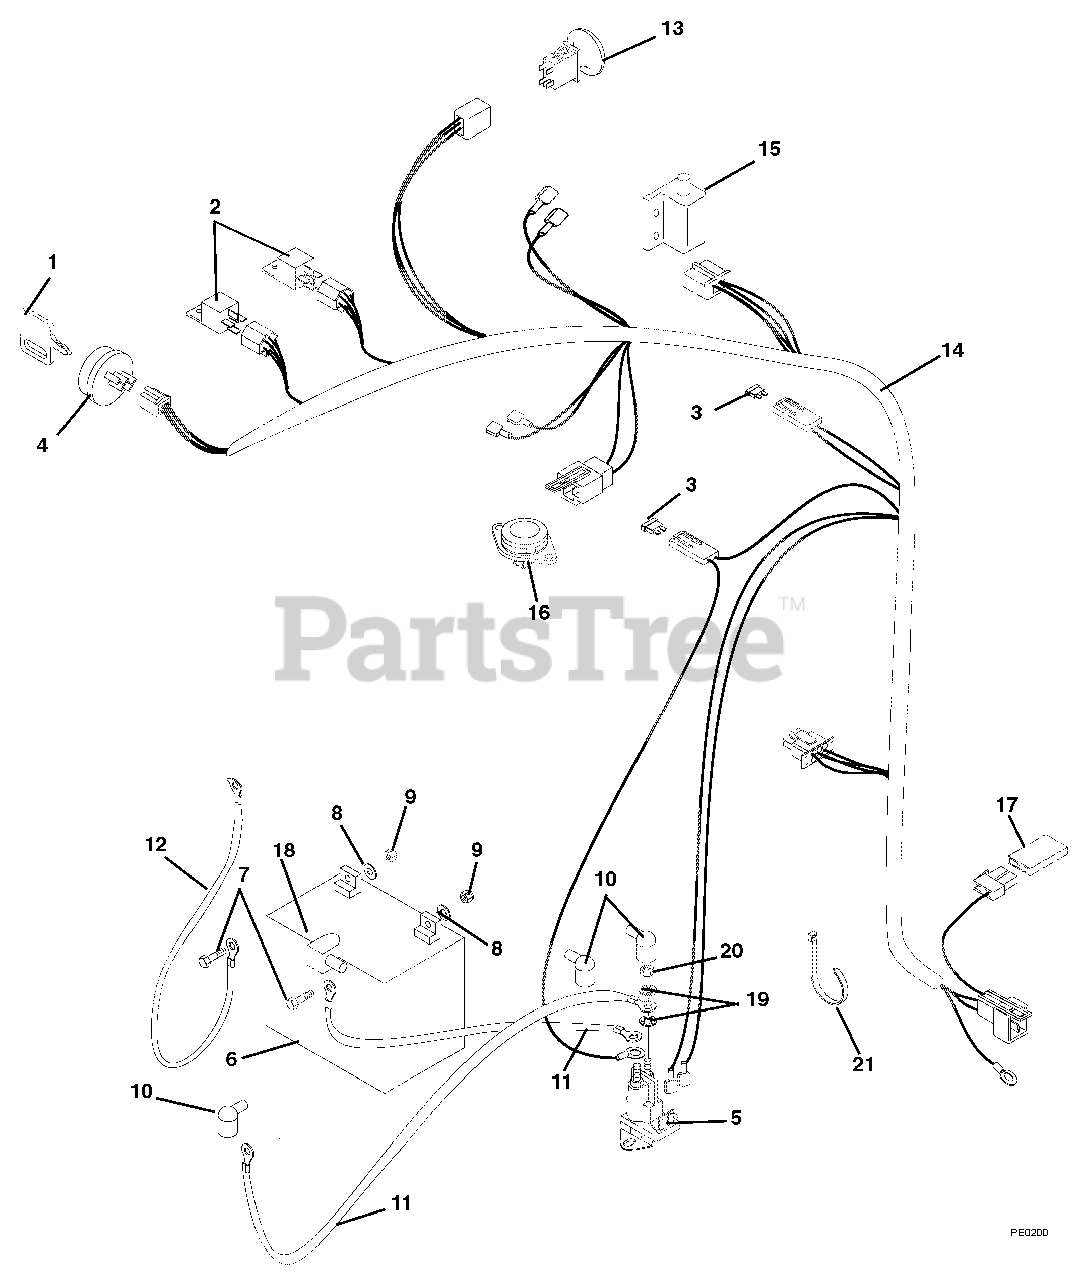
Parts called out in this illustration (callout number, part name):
1	KEY -W/CAP
2	RELAY
3	FUSE-25 AMP ATC TYPE
4	KEY SWITCH
5	SOLENOID, HP RTV
6	Battery, Exide Sealed Maintenance Free U1-250 (Purchase replacement locally)
7	@BLT-HEX .25-20X.75 GR5 YWZC
8	@WSHR-FL-STL.281X.62X.065 YWZC
9	NUT-KEPS .250-20
10	BOOT, EYELET TERMINAL
11	STARTER CABLE 13"
12	GROUND CABLE .31X22.00X.31
13	SWITCH, CLUTCH
14	WIRE HARNESS
15	SWITCH- DOUBLE POLE N.O./N.O.
16	SWITCH- SNAP MTG N.O.
17	DIODE, CONNECTOR SHELL
18	INSULATOR
19	WSHR-LOCK INT .31 YWZC
20	NUT-JAM .31-24 YWZC
21	CABLE TIE LG 5-1/2
